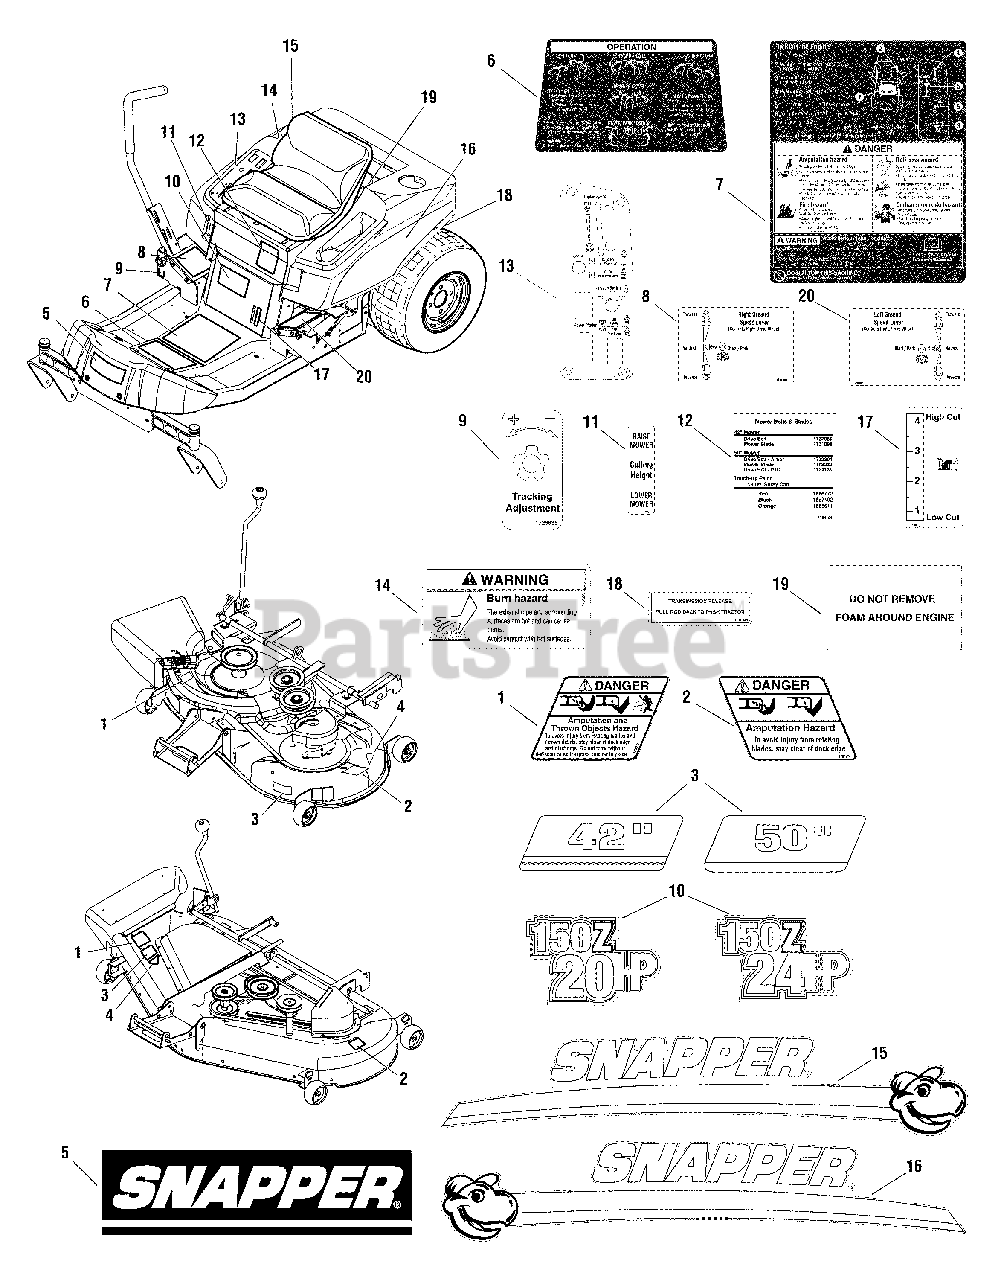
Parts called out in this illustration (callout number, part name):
1	DECAL, Danger Do Not Operate without Deflector
2	DECAL, Danger Do Not Put Hands/Feet in Mower
3	DECAL, 42"
3	DECAL, 50"
4	DECAL, OPEI Certified ANSI
5	DECAL, Snapper Logo
6	DECAL, Operator Instructions Front
7	DECAL, Operator Intructions Bottom
8	DECAL, Handle Control R.H.
9	DECAL, Tracking Adjustment
10	DECAL, Model 150Z, 20HP
10	DECAL, Model 150Z, 24HP
11	DECAL, Height of Cut
12	DECAL, Belt & Blade
13	DECAL, Instrument Panel
14	DECAL, Warning Burn Hazard
15	DECAL, Seat Deck R.H. Snapper
16	DECAL, Seat Deck L.H. Snapper
17	DECAL, Height of Cut w/out Best Cut
18	DECAL, Transmission Release Instructions
19	DECAL, Do Not Remove Foam Around Engine
20	DECAL, Handle Control L.H.
